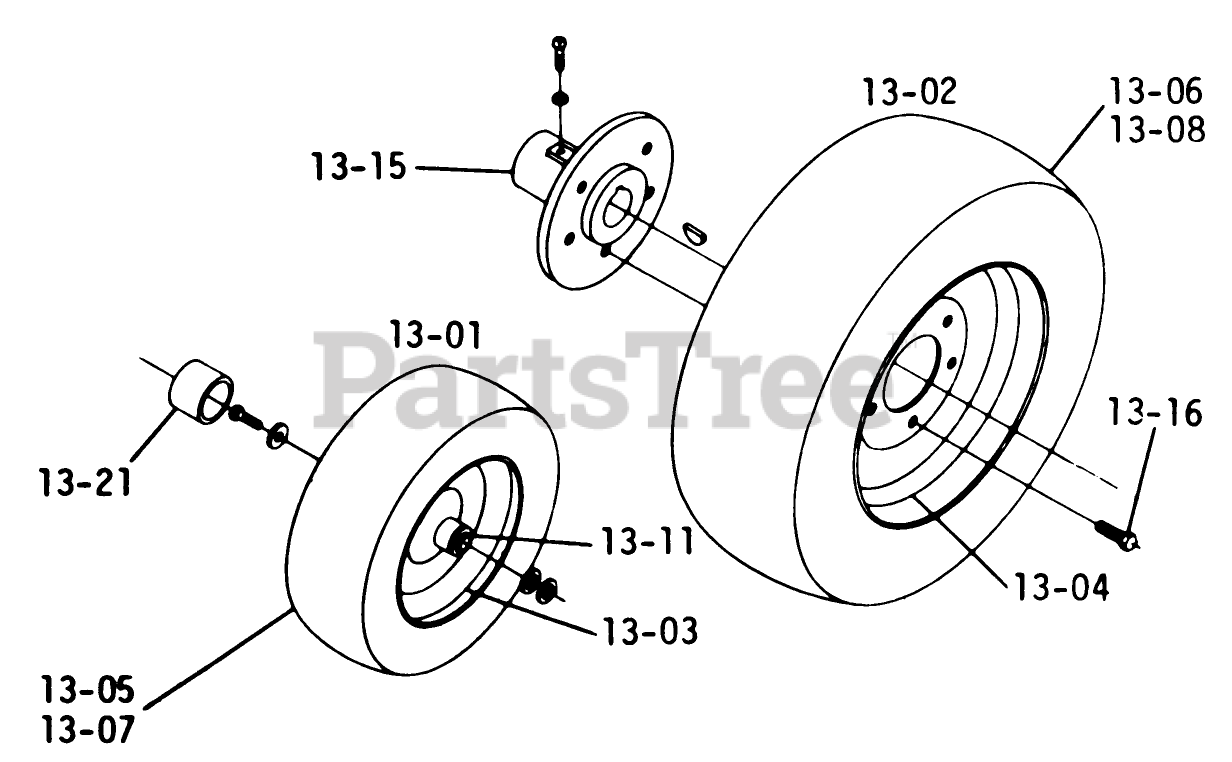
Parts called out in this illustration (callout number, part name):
13-01	Wheel-Complete
13-02	Tire & Wheel Assy
13-03	WHEEL
13-04	Wheel
13-05	TIRE TURF SAVER 16X6.50-8
13-06	TIRE 22 X 7.50-12
13-07	Tube
13-08	TUBE-INNER
13-11	Bearing
13-15	Hub-Wheel
13-16	Lug Nut
13-21	HUB CAP
